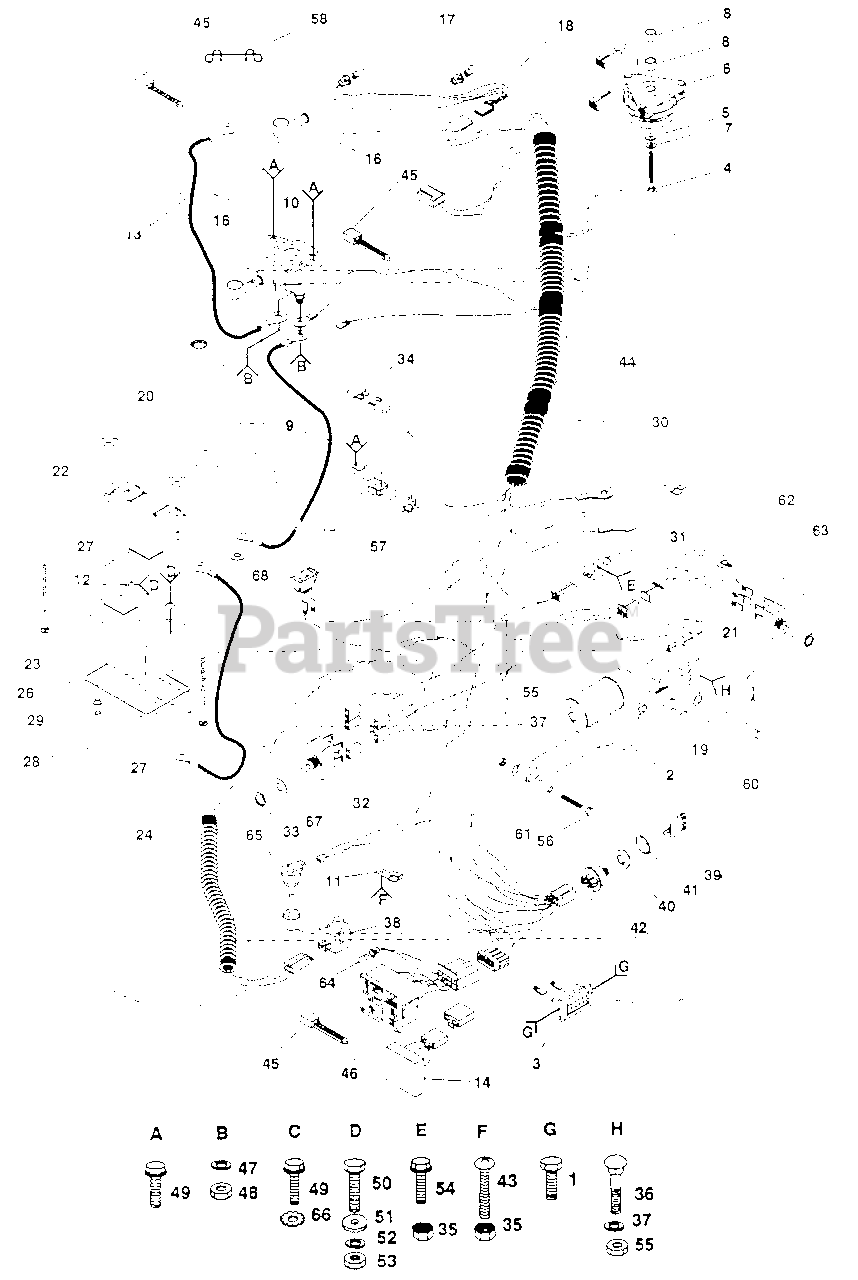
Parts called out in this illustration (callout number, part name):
1	Screw # 10-24 x 1/2
2	Actuator, Electric
3	Meter, Hour
4	Bolt, Hex 7/16-20 x 1-1/2 Gr. 8
6	Clutch, Electric
7	Washer, Lock 7/16
8	Spacer, Clutch
9	Cable, Battery
10	Solenoid
11	Clip, Insulated
12	Battery Caps
13	Cable, Starter
14	Sensor, Low Voltage
15	Switch, Light
16	Cover, Terminal
17	Bulb, Light
18	Harness, Light Socket
19	Bracket Assembly, Actuator
20	Nut, Wing 1/4-20
21	Spring, Retainer
22	Guard, Terminal
23	Battery
24	Cable Ground
26	Tray, Battery
27	Bolt, Carriage 1/4-20 x 7-1/2
28	Tube, Plastic
29	Clamp, Hose
31	Switch, Interlock
32	Switch, P.T.0.
33	Nut, Hex
35	Nut, Keps #10-32
36	Bolt, Carriage 3/8-16 x 1
37	Washer, Lock 3/8
38	Switch, Seat
40	Nut, Ignition
41	Bezel, Ignition
42	Switch, Ignition
43	Screw, Slot, Pan HD #10-32 x 1/2
44	Harness, Ignition
45	Cable Tie
46	Light Package
47	Washer, Lock 1/4
48	Nut, Hex Jam 1/4-20
49	Screw, Hex Washer Hd. Cutting 1/4-20 x 1/2
50	Bolt, Hex Hd. 1/4-20 x 3/4
51	Washer 9/32 x 5/8 x 16 Gauge
52	Washer, Lock 1/4
53	Nut, Hex 1/4-20
54	Screw, Hex Washer Hd. #10-32 x 1-1/2
55	Nut, Fin Hex 3/8-16
56	Bolt, Fin Hex 3/8-16 x 2-1/4
57	Assembly, Relay
60	Pin, Actuator
62	Switch Assembly, Lift
63	Washer, Lock
64	Bulb, Dashboard, Light
65	Sensor, Low Fuel
66	Washer, Lock, External Tooth
67	Washer 17/32 x 3/4 x 16 Ga.
68	Washer, Lock, Int. tooth 1/4
